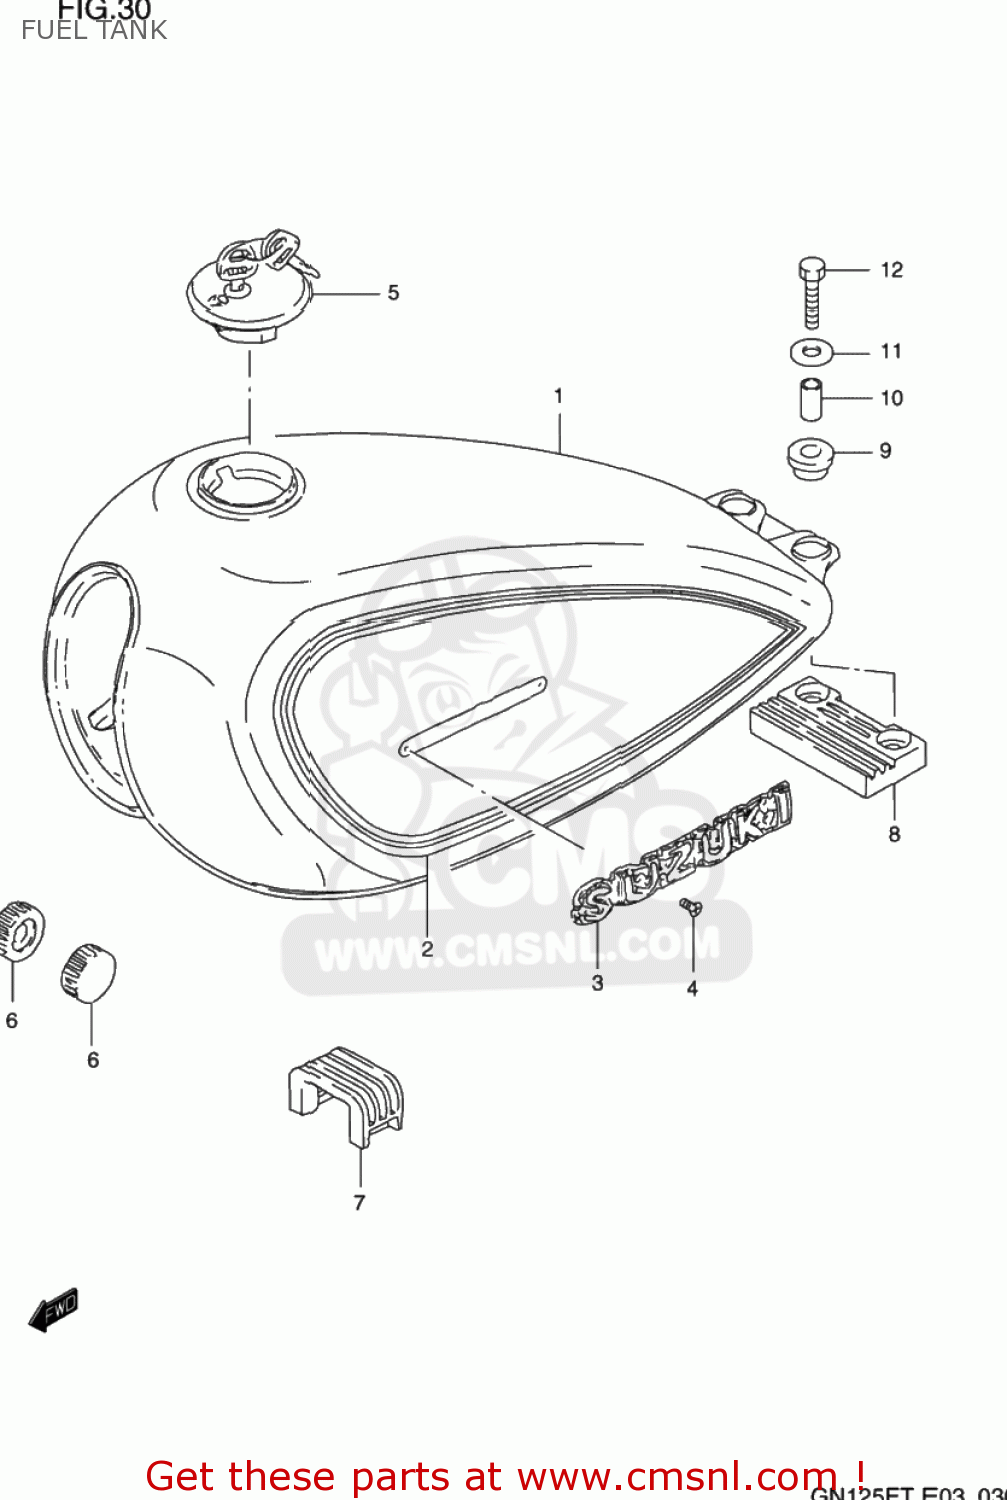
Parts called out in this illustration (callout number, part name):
1	TANK ASSEMBLY,FUEL
2	TAPE SET,FUEL TANK
3	EMBLEM,FUEL TANK
4	SCREW
5	CAP SET,FUEL TANK
6	CUSHION
7	CUSHION,FUEL TANK UPR FR
8	CUSHION,TANK RR NO.1
9	CUSHION
10	SPACER(6.5X10.5X22.5)
11	WASHER(6,5X22X1.6)
12	BOLT(6X35)
